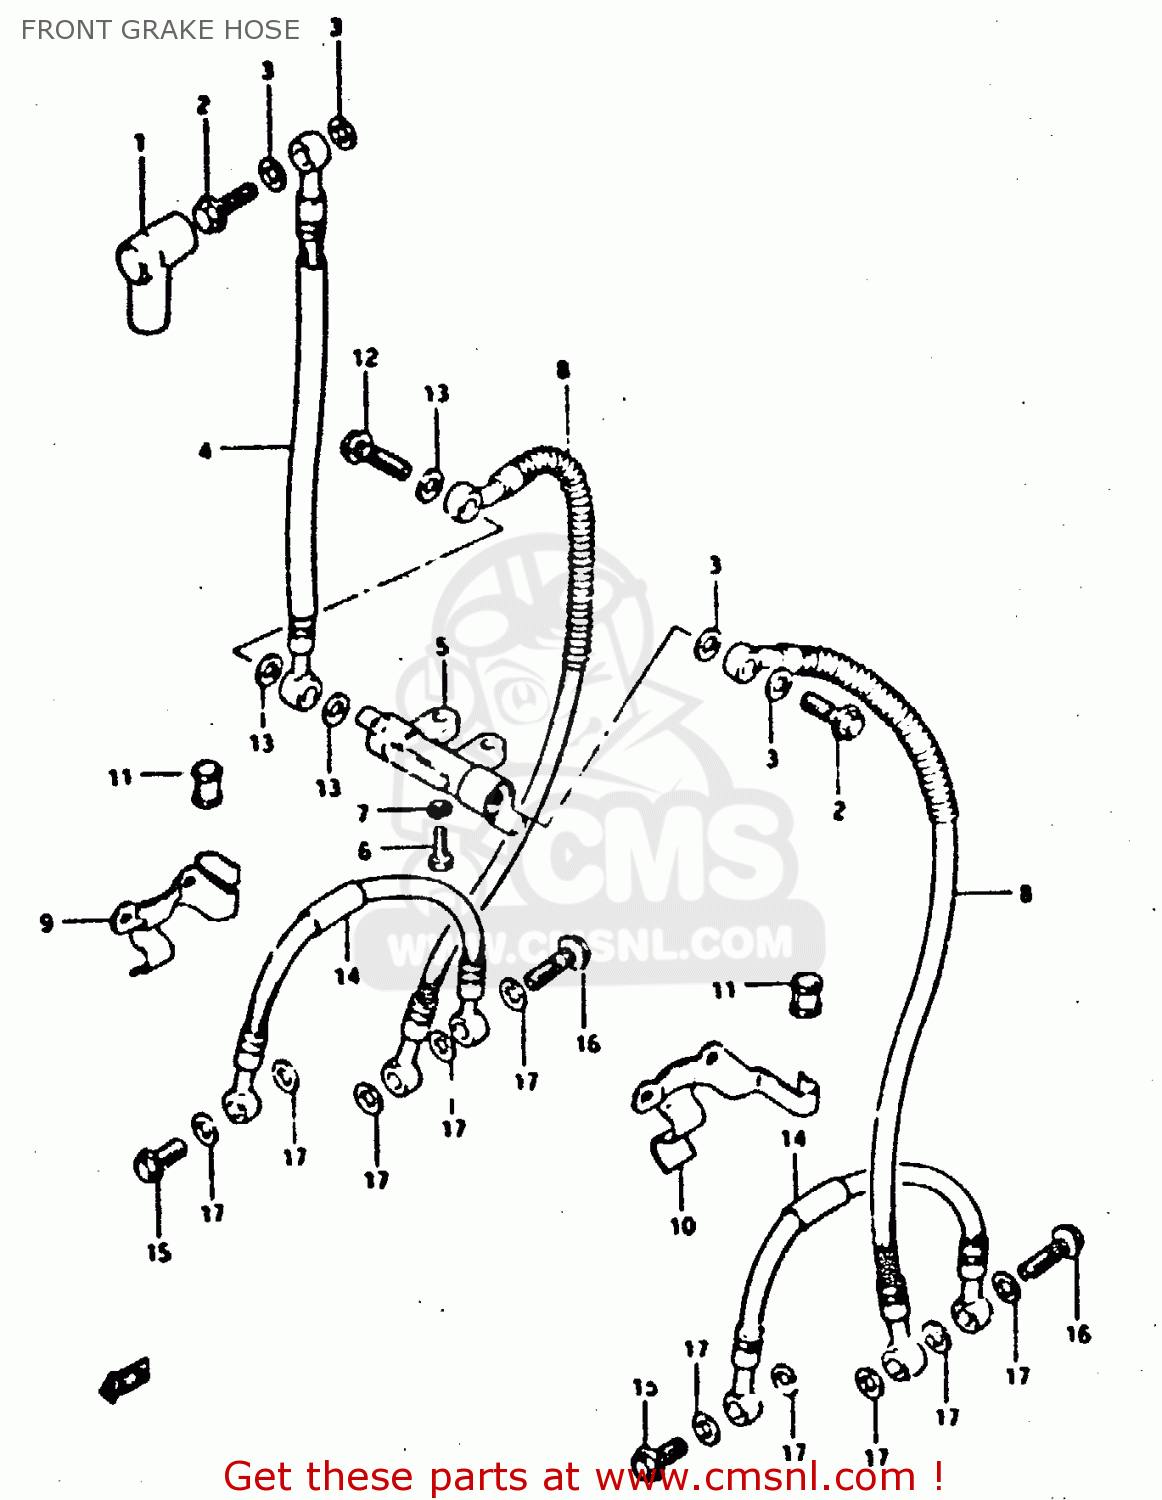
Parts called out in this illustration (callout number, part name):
1	BOOT
2	BOLT,UNION
3	WASHER
4	HOSE,BRAKE NO.1
5	JOINT,BRAKE HOSE
6	BOLT
7	LOCK WASHER
8	HOSE,FRONT BRAKE
9	CLAMP,FRONT BRAKE HOSE
10	CLAMP,FRONT BRAKE HOSE
11	BUSH,BRAKE HOSE GUIDE,NO.2
12	BOLT,UNION
13	WASHER
14	HOSE, UNTI NOSE
15	BOLT,UNION
16	BOLT,UNION
17	WASHER
